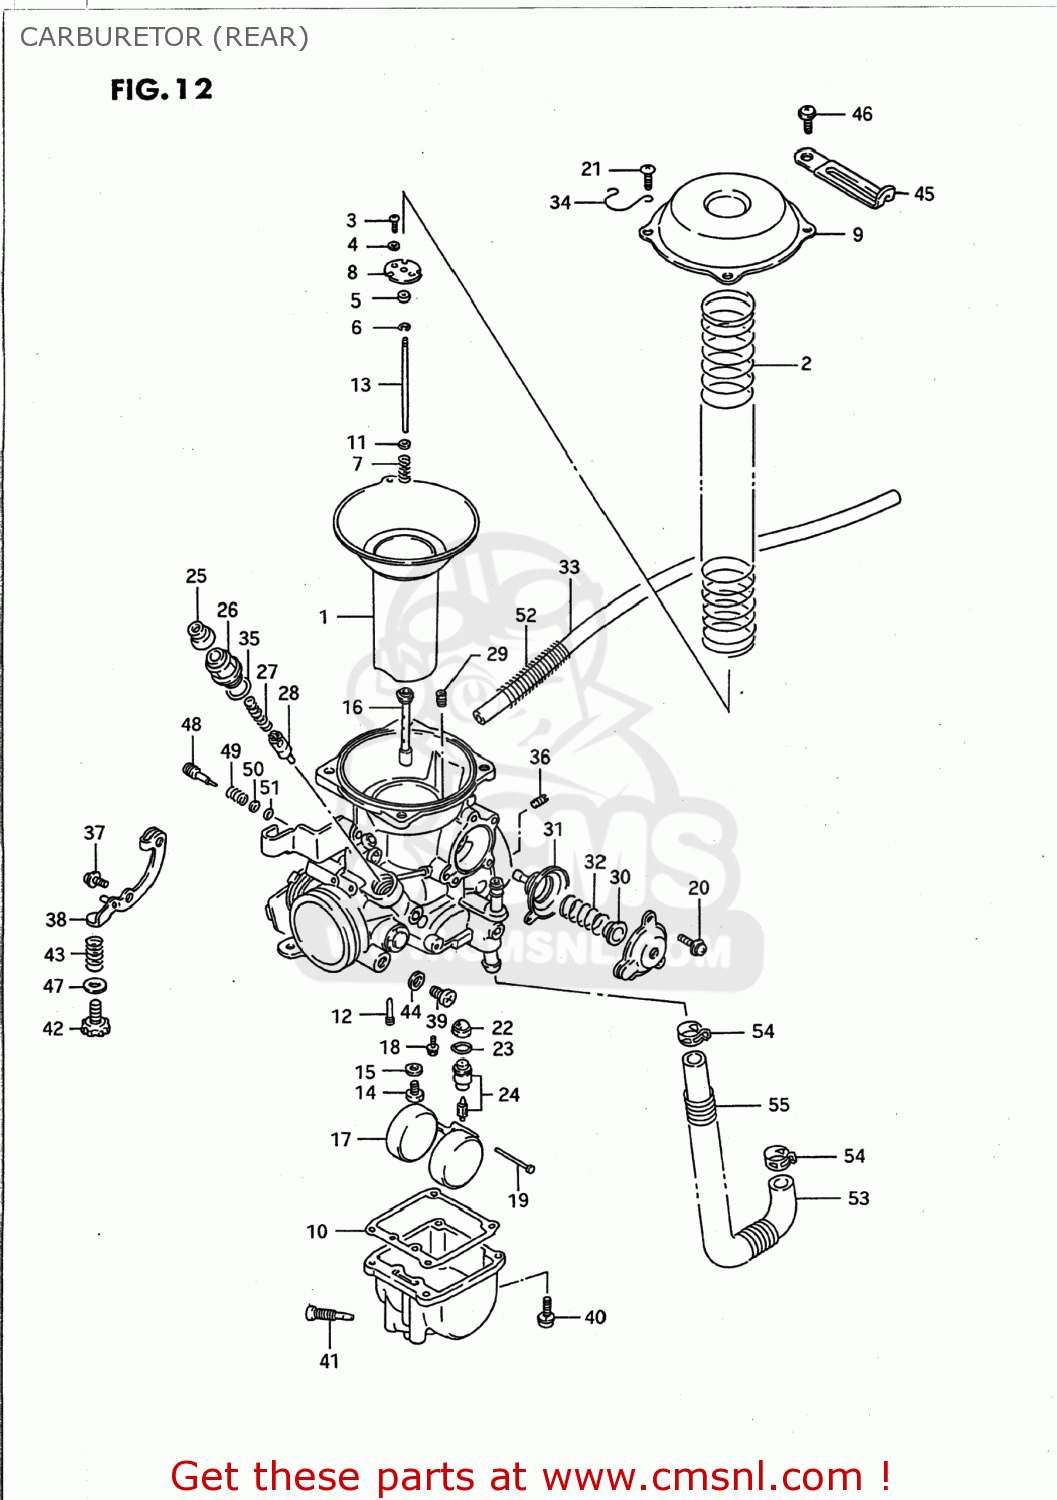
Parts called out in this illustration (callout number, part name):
1	DIAPHRAGM,CARBURETOR
2	SPRING,DIAPHRAGM
3	SCREW
4	LOCK WASHER
5	RING
6	CLIP
7	SPRING
8	PLATE
9	COVER,DIAPHRAGM
10	GASKET,FLOAT CHAMBER (NAS)
11	WASHER
12	JET,PILOT
13	NEEDLE,JET
14	JET,MAIN(140)
15	WASHER,NEEDLE NOZZLE
16	JET,NEEDLE
17	FLOAT
18	SCREW
19	PIN,FLOAT
20	SCREW
21	SCREW
22	FILTER
23	O-RING,NEEDLE VALVE
24	VALVE ASSY,NEEDLE
25	CAP
26	HOLDER,GUIDE
27	SPRING
28	PLUNGER,STARTER
29	JET,AIR
30	PLATE
31	DIAPHRAGM ASSY
32	SPRING
33	HOSE ASSEMBLY
34	CLIP
35	O RING
36	JET
37	SCREW
38	LEVER ASSEMBLY
39	SCREW
40	SCREW
41	PLUG
42	ADJUSTER
43	SPRING
44	WASHER
45	CLIP
46	SCREW
47	WASHER
48	HOSE
49	SPRING
50	HOSE,FUEL PUMP & CARBURETOR
51	CLAMP
52	SPRING
